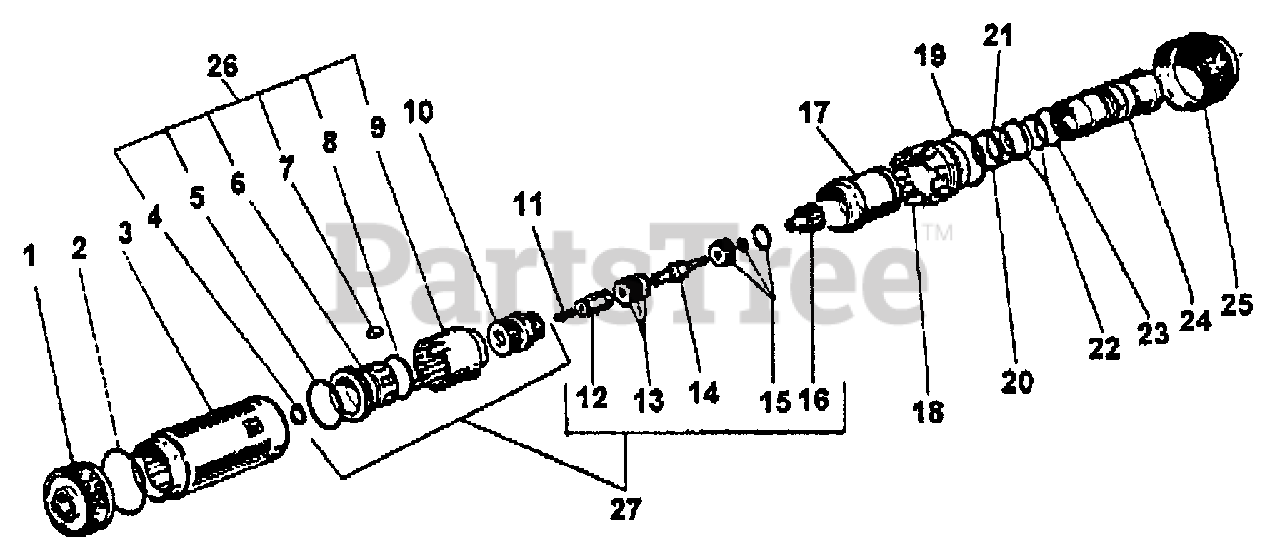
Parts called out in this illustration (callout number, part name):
1	CAP, FRONT
2	O-RING
3	KNOB, ADJUSTMENT
4	RING, RETAINING
5	O-RING
6	ROTOR
7	BEARING, ROLLER
8	O-RING - .797 X.103
9	CLUTCH
10	RINGNUT
11	NOZZLE - RED
12	HOLDER, NOZZLE
13	BEARING, BALL
14	CRANKSHAFT ASSY
15	SEAL ASSY
16	ROTOR
17	CYLINDER, DIFFUSER
18	DIFFUSER, LOW PRESSURE
19	O-RING
20	RING, ANTI-EXTRUSION
21	O-RING
22	SEAL, RING
24	BODY, DIFFUSER
25	RING, LOCK
26	KIT, (PARTIAL) ROTOX REBUILD
27	ROTOX REBUILD KIT
